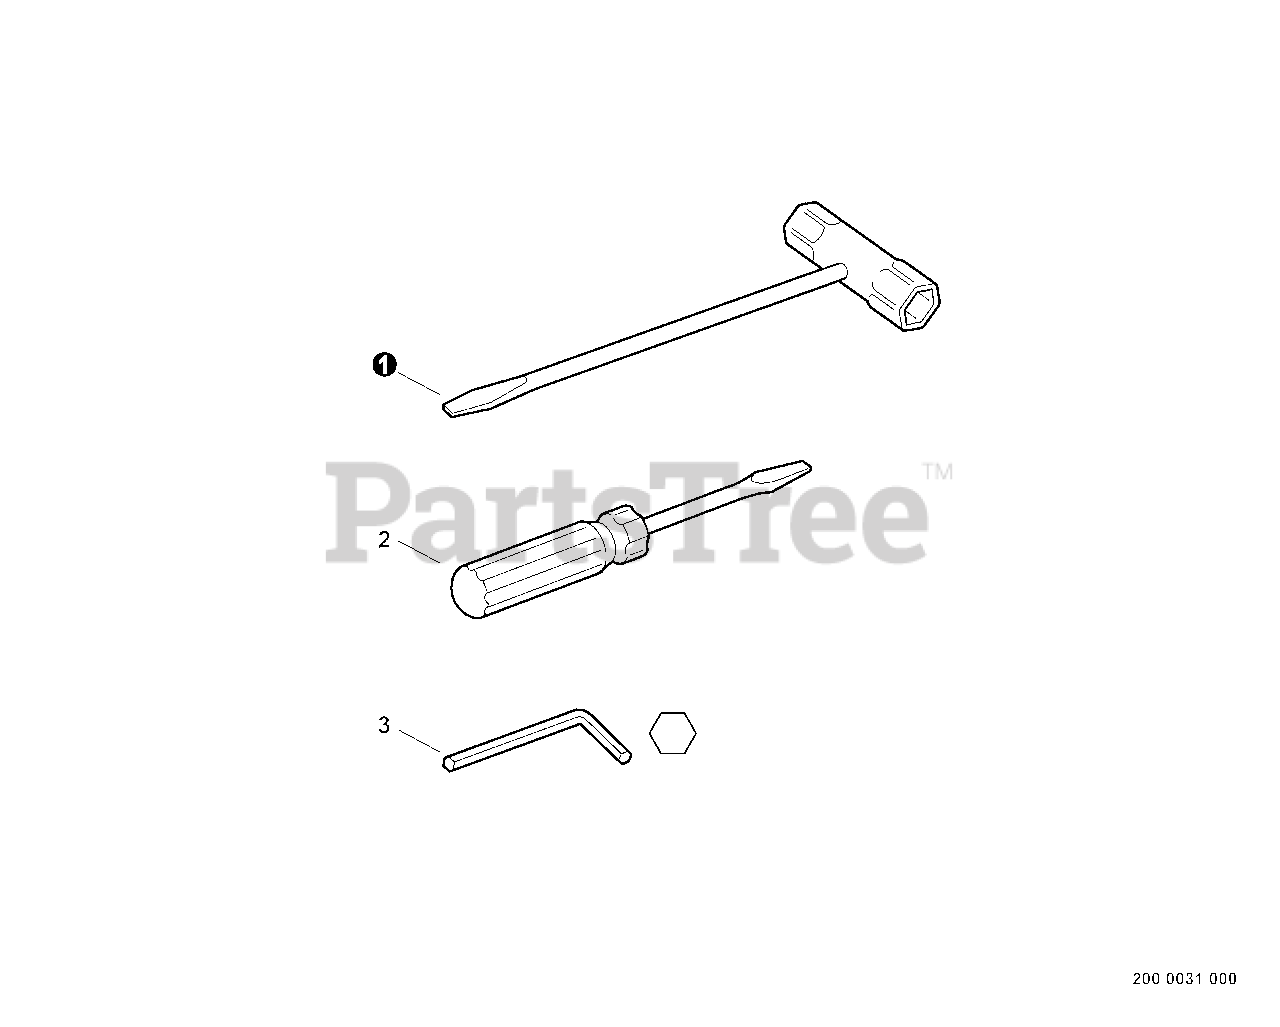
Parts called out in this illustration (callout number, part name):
1	T-WRENCH - 13X19mm
2	SCREWDRIVER
3	HEX KEY - 4mm
